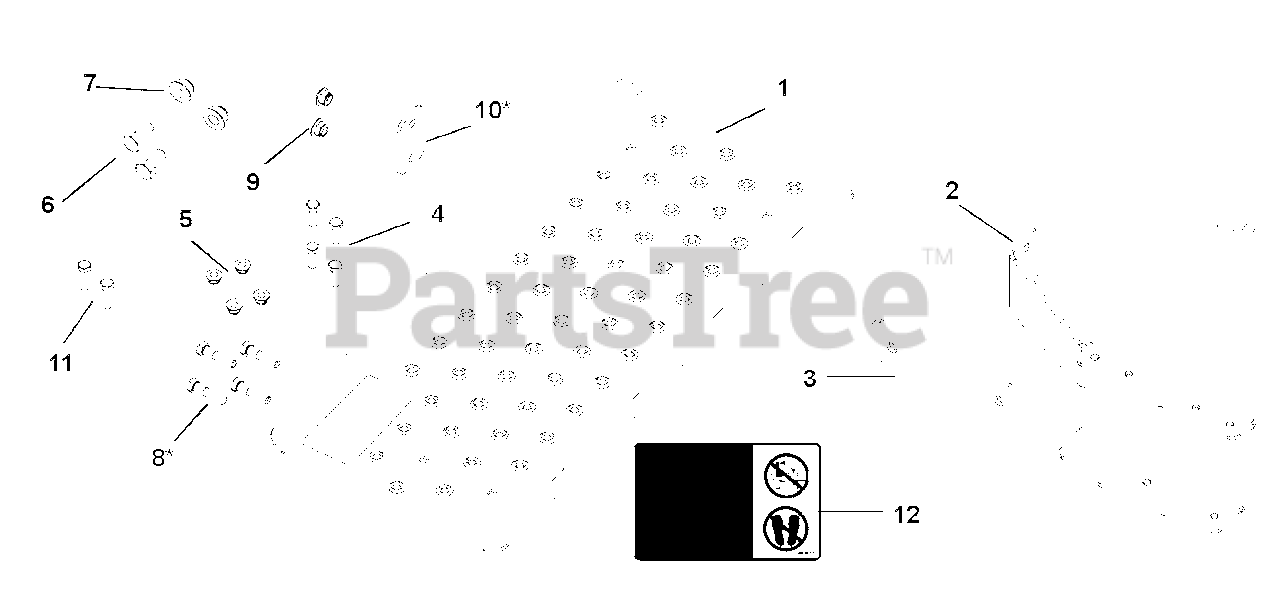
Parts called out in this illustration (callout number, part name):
1	Bracket, Work Table
2	Bracket, Rear Table Mount
3	Bracket, Front Table Mount
4	Bolt, Round Head Square Neck .312-18 x 1
5	Nut, Nyloc Flange .312-18
6	Bolt, Hex .50-13 x 1
7	Nut, Locking Top Flange .50-13
8	Bolt, Hex .38-16 x 1.5
9	Nut, Locking Top Flange .38-16
10	Spacer Plate, Work Table
11	Bolt, Hex .38-16 x 1.25
12	Decal, Splitter Table
